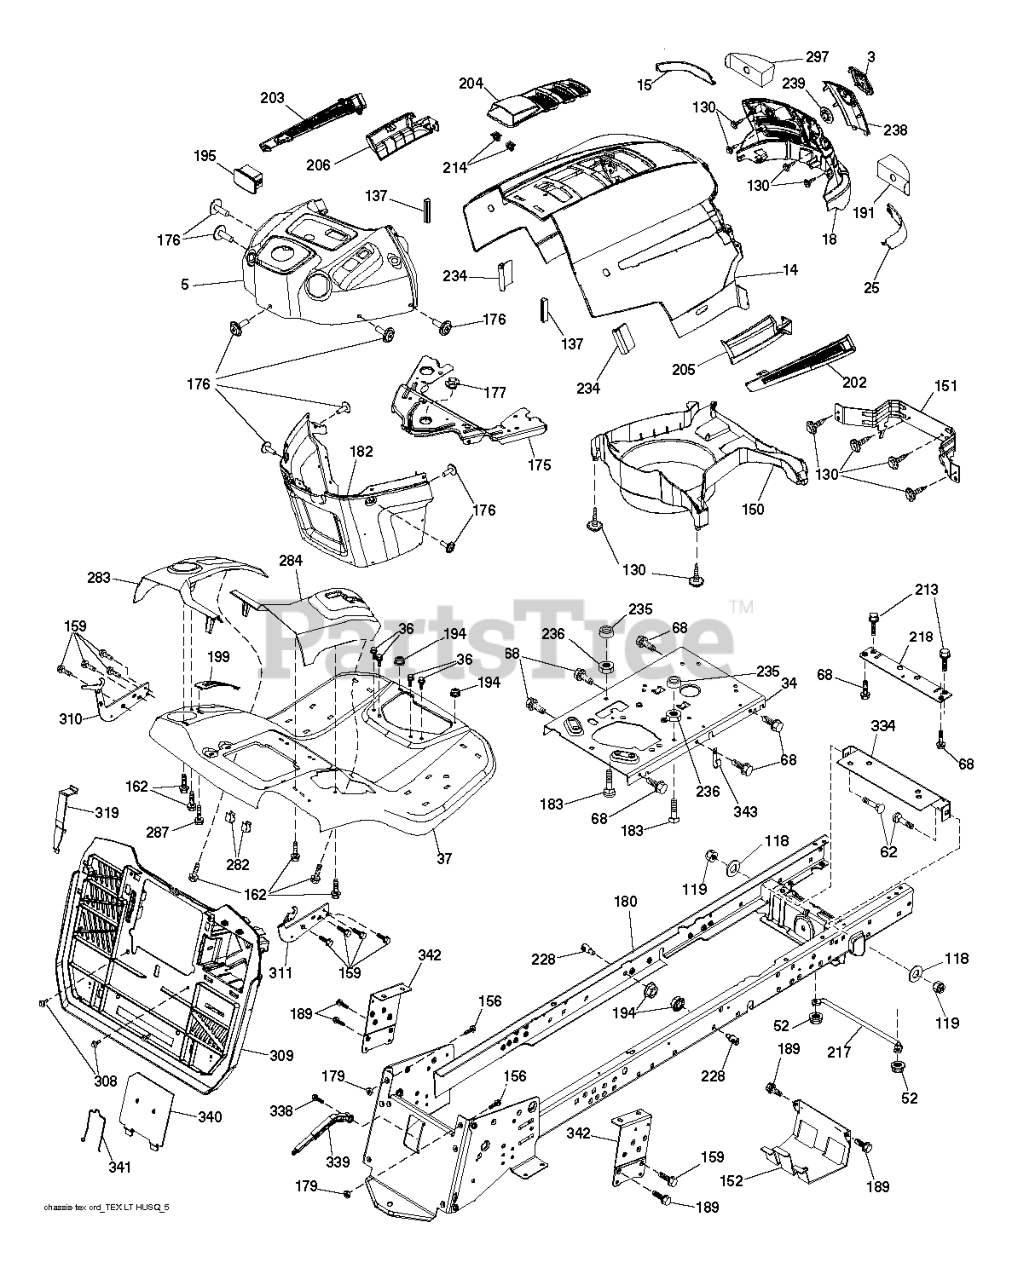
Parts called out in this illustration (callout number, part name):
3	RP LOGO
5	SUBASM.DASH.UPPER.W/BUMPER
14	HOOD.HUSQVARNA.LT.ORANGE
15	LENS.HUSQVARNA LT.RH
18	GRILLE.SVC.HUSQVARNA.GREY
25	LENS.HUSQVARNA LT.RH
34	PLATE PLATE ENGINE
36	SCREW 5/16"
37	FENDER.TEX.SRD.CRD.FRN.GUARDS
52	LOCKNUT
62	BOLT D
68	Screw 5/16-18 x 1/2 Hex, Self Tapping 5/16-18 x 1/2
118	WASHER
130	SCREW.#10 X 0.750.BOS
137	BUMPER DASH
151	BRACKET PIVOT
152	SHIELD.BROWNING.W/TEX
156	BOLT
159	SCREW, 3/8-16X3/4
162	SCREW.HI-LO.CONSOLE
175	CROSSMEMBER
176	SCREW.#10-24X5/8.RN.QU
177	BUSHING STEERING
182	DASH.LOWER.PREDATOR LT
183	BOLT.5/16-18X1-1/4 FULL THD
189	SCREW
191	INSERT.REFLECTIVE.RH.
194	NUT LOCK HEX FLANGE 5/16-18
195	PLUG.TEX.DASH.SVC.MINDER.GREY
199	PLATE DECK LIFT
202	VENT.SIDE.HUSQVARNA.LT.RT
203	VENT.SIDE.HUSQVARNA.LT.LFT
204	SUBASM.TOP.VENT.HUSQ.LT
205	SKIRT.SIDE.HUSQVARNA.LT.RT
206	SKIRT.SIDE.HUSQVARNA.LT.LEFT
213	BOLT
214	CLIP.RETAINER.TINNER.
217	ROD.PIVOT.HOOD
218	X-PIECE.HOOD.STOP.NON/
228	STUD.FASTNER.W/ANTI-ROTATE
234	BUMPER.HOOD.TEX.HUSQVARNA
235	SPACER FENDER
236	NUT.CENTERLOCK.5/16-
238	TRIM.HUSQ LT.668
282	CLIP.RETAINER.CONSOLE.LT.HUSQ
283	CONSL.DECKLIFT.LH.SRD.TEX.CRD
284	CONSL.SHIFT.GEAR.RH.SRD.GREY
287	SCREW 1/4X20
297	INSERT REFLECTIVE
308	BOLT.5/16-18UNCX3/4 W/SEMS.BLK
309	BACKPLATE.TEX.CRD
310	LH.ADJUST.HANGER.BRACKET.ASM
311	RH.ADJUST.HANGER.BRACKET.ASM
319	BRACKET.ACTUATOR.BAGGER.SRD
334	BRACKET.ENGINE
338	BOLT BOLT SHOULDER
339	LEVER.BAGGER.FULL.TEX.
340	DOOR.PNT.BATTERY.TRY.TEX.CRD.
341	LATCH
342	SUPPORT SUPPORT FENDER
343	CLIP CLIP
